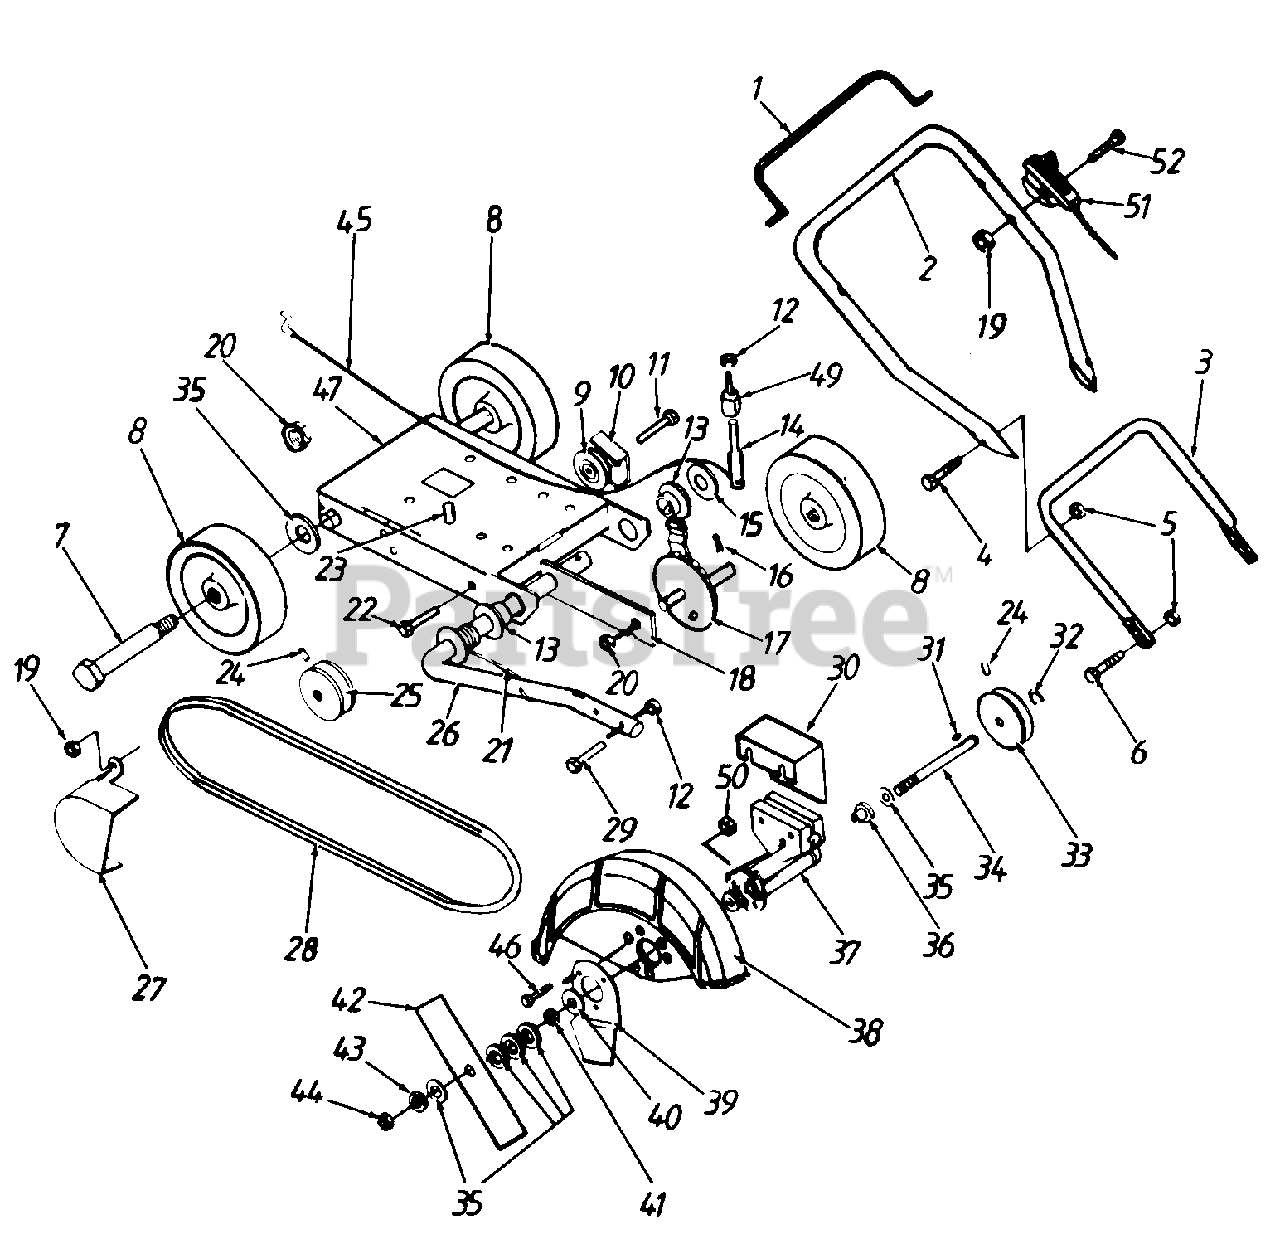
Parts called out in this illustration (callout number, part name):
1	Lever-Depth Control
2	Upper Handle
3	Lower Handle
4	Hex Bolt 5/16-18 x 1.5"
5	Hex Keps L-Nut 5/16-18 Thd.
6	Hex Bolt 5/16-18 x .625"
7	Wheel Bolt
8	Wheel 6"
9	Idler Pulley
10	Bracket-ldler Pulley
11	Bolt
12	Hex L-Nut 5/16-18 Thd.
13	Bushing
14	Arm-Pivot Rod
15	Flat Washer 5/8" I.D.
16	Cotter Pin 1/8 x 3/4
17	Adjustor Assembly
18	Arm-Front Wheel
19	Hex L-Nut 1/4-20 Thd.
20	Hex Keps L-Nut 3/8-16 Thd.
21	Spring-Cutterhead
22	Hex Bolt 5/16-18 x 1"
23	Engine Bolt
24	Locking Set Screw 5/16-18
25	Pulley Engine
26	Rod Cutterhead
27	Belt Guard
28	V-Belt
29	Hex Bolt 5/16-18 x 1.51'
30	Belt Guard
31	Woodruff Key
32	Retaining Ring
33	Pulley Cutterhead
34	Shaft Cutterhead
35	Flat Washer .0631 Thk.
36	Bushing Cutterhead
37	Housing Cutterhead Shaft
38	Blade Guard
39	Edge Guide
40	Flat Washer .035 Thk.
41	Heavy Hex Jam Nut 3/8-24
42	9" Replacement Blade
43	Spring L-Wash. 818n I.D.
44	Hex Nut 3/8-24 Thd.
45	Cable Depth Control
46	Hex Bolt #10-24 x .75"
47	Base Edger Frame
49	Spacer Pivot Arm
50	Nylok Nut #10-24
51	Throttle Control
52	Hex Bolt 1/4-20 x 1.5
